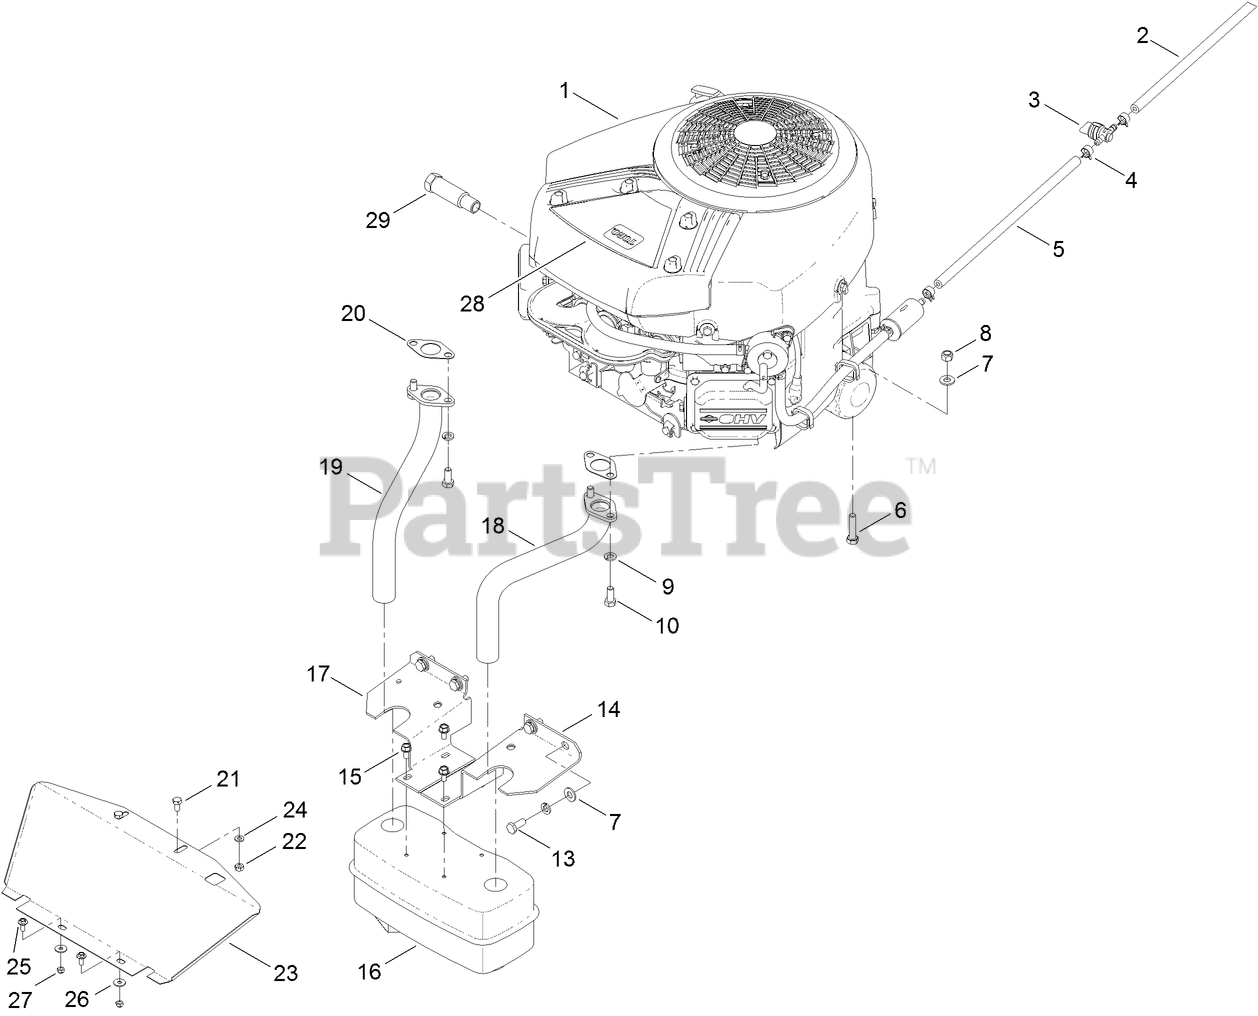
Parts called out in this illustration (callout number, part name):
2	LINE-FUEL
3	VALVE-TANK, FUEL
4	CLAMP-LINE, FUEL
6	SCREW-HH
7	WASHER-PLAIN
8	NUT-LOCK, NI
9	WASHER-SPRING
10	SCREW-HH
13	SCREW-HH
14	GUARD-MUFFLER, LH
16	MUFFLER
17	GUARD-MUFFLER, RH
18	TUBE-EXHAUST, LH
19	TUBE-EXHAUST, RH
20	GASKET-EXHAUST
21	SCREW-HH
22	NUT-LOCK
23	SHIELD-HEAT
24	WASHER-FLAT
26	WASHER-FLAT
27	NUT-LOCK
28	DECAL-ENGINE
29	COUPLER-DRAIN, OIL
